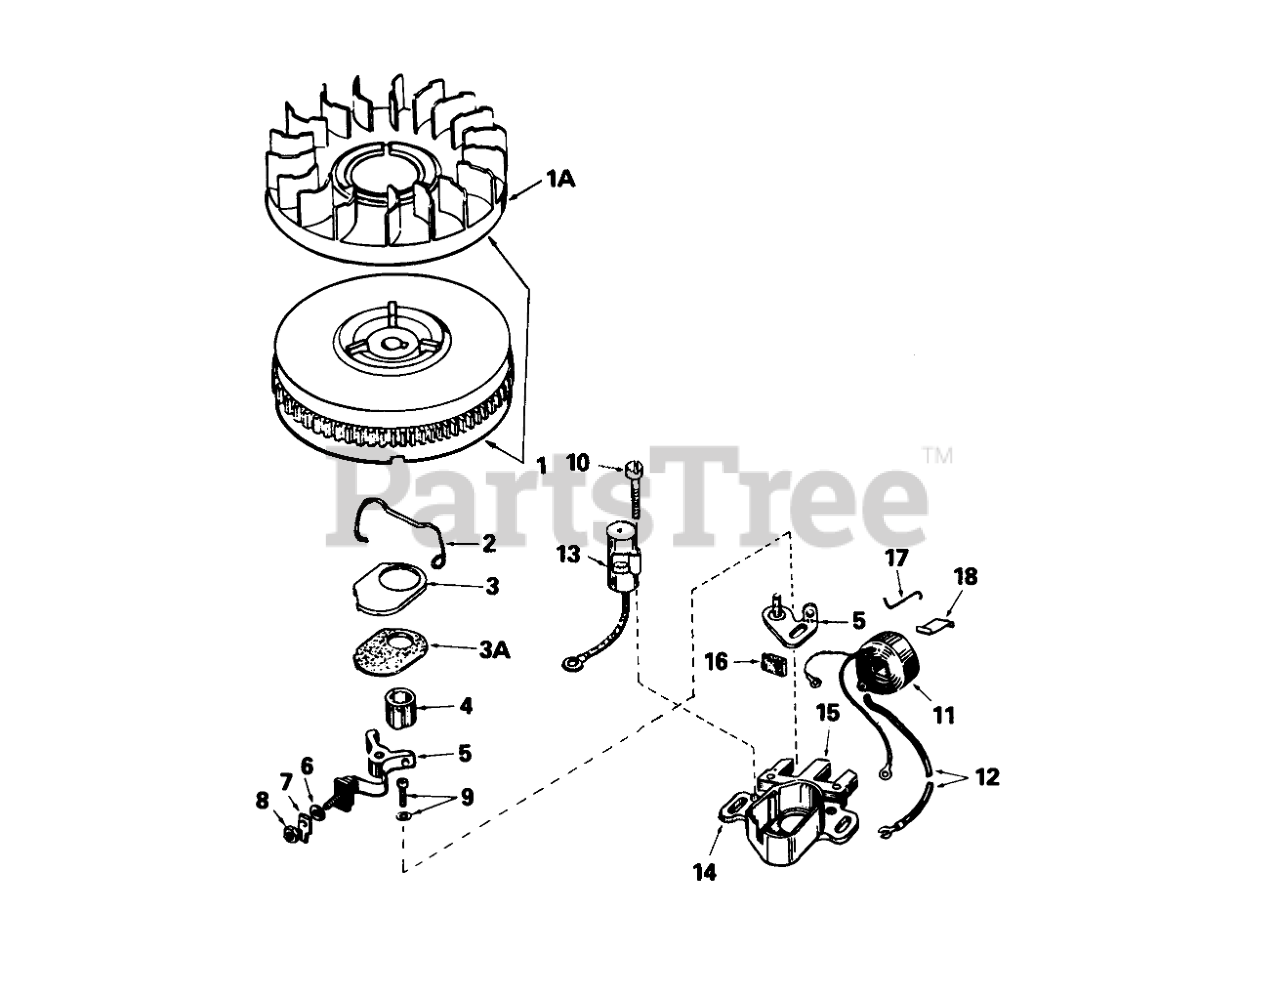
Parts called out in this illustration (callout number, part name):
1	Flywheel (Incl. Ref. #1A)
1A	Fan
2	Spring Breaker Box
3	Cover-Dust
3A	Gasket-Dust Cover
4	Cam-Breaker
5	Breaker Assy.
6	Washer
7	Terminal, Ground
8	DECAL
9	Breaker Screw
10	Condenser Screw
11	Coil Assy. (Incl. Ref. #12)
12	Wire, Lead
13	Condenser
14	Core & Plate
15	Stator Assy. (Incl. Ref. #2, 3, 3A, 5 thru 14, 16 & 17)
16	Felt,Cam Wiper
17	Clip, Coil
